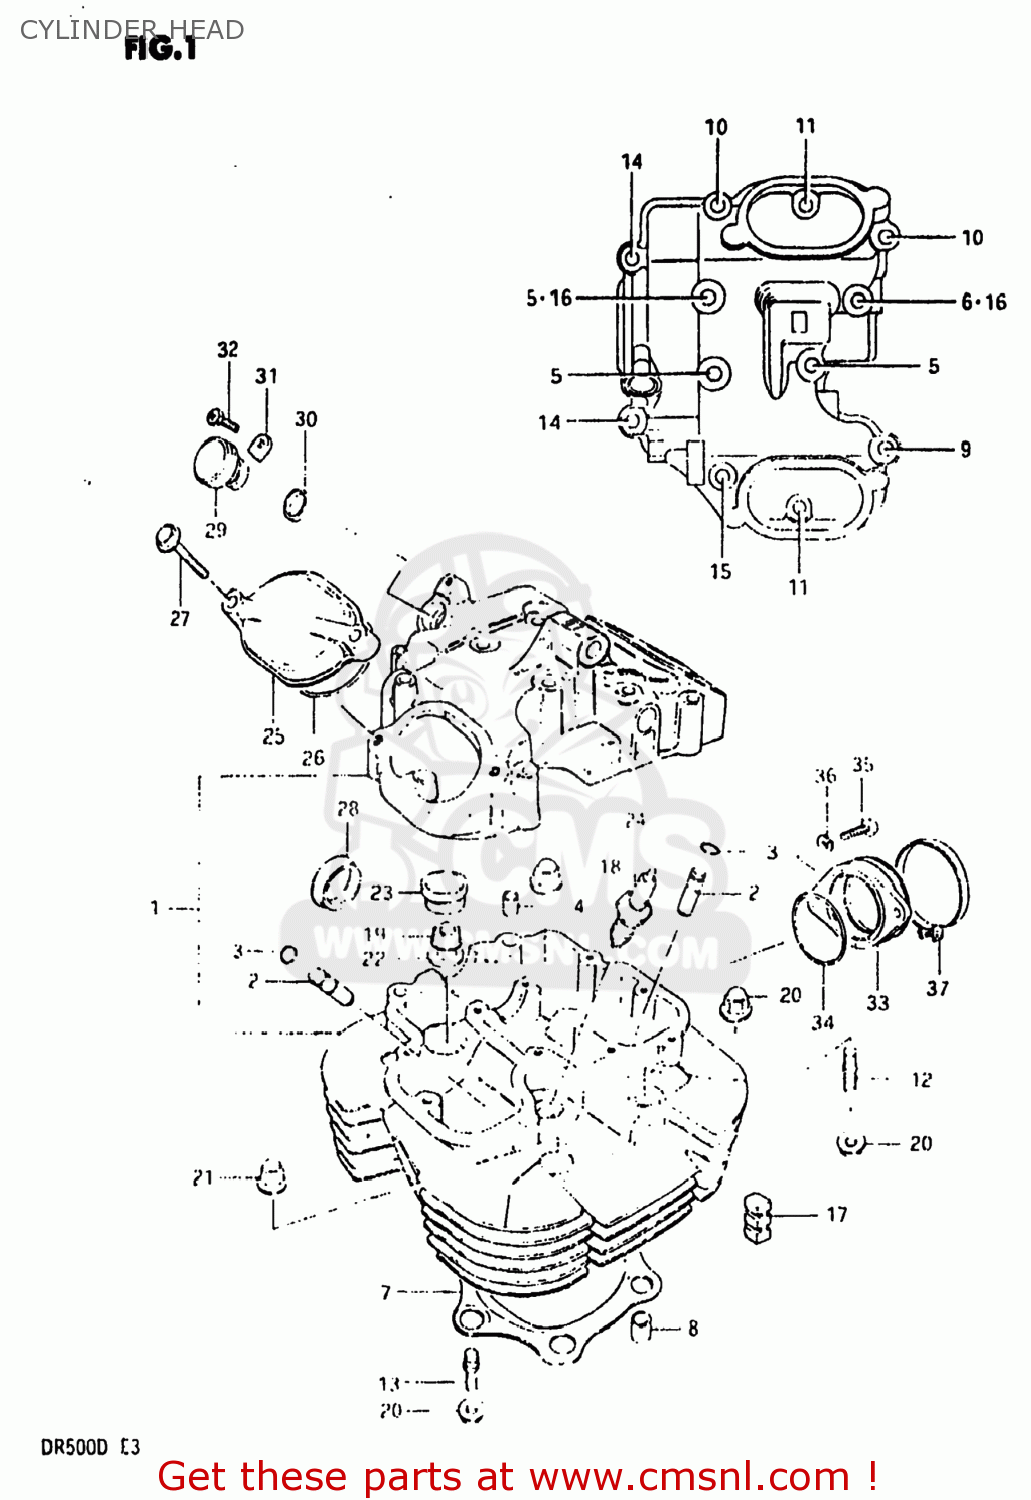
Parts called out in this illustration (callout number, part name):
1	HEAD,CYLINDER (4-VALVE)
2	GUIDE,VALVE
3	RING,SNAP
4	PIN(6.2X8X11)
5	BOLT (6X60)
6	BOLT 6X55
7	GASKET,CYLINDER HEAD (NAS)
8	PIN
9	BOLT 6X50
10	BOLT (6X45)
11	BOLT 6X30
12	STUD
13	STUD
14	BOLT
15	BOLT (6X60)
16	GASKET (NAS)
17	PAD,CYLINDER
18	NUT
19	NUT
20	NUT 8MM
21	NUT
22	GASKET(10.5X22X2) (NAS)
23	NUT,CYLINDER HEAD SEAL
24	SPARK PLUG D8EA
25	CAP,INSPECTION HOLE
26	O RING(D:2.4,ID:23)
27	BOLT
28	PLUG(OD:30)
29	PLUG,TACH GEAR SLEEVE HOLE
30	SEAL,TACHOMETER DRIVEN
31	PLATE,TACH DRIVE GEAR SLEEVE
32	SCREW(5X12)
33	PIPE,INTAKE
34	O-RING (D:2.4 ID:45.7)
35	SCREW
36	LOCK WASHER
37	CLAMP
